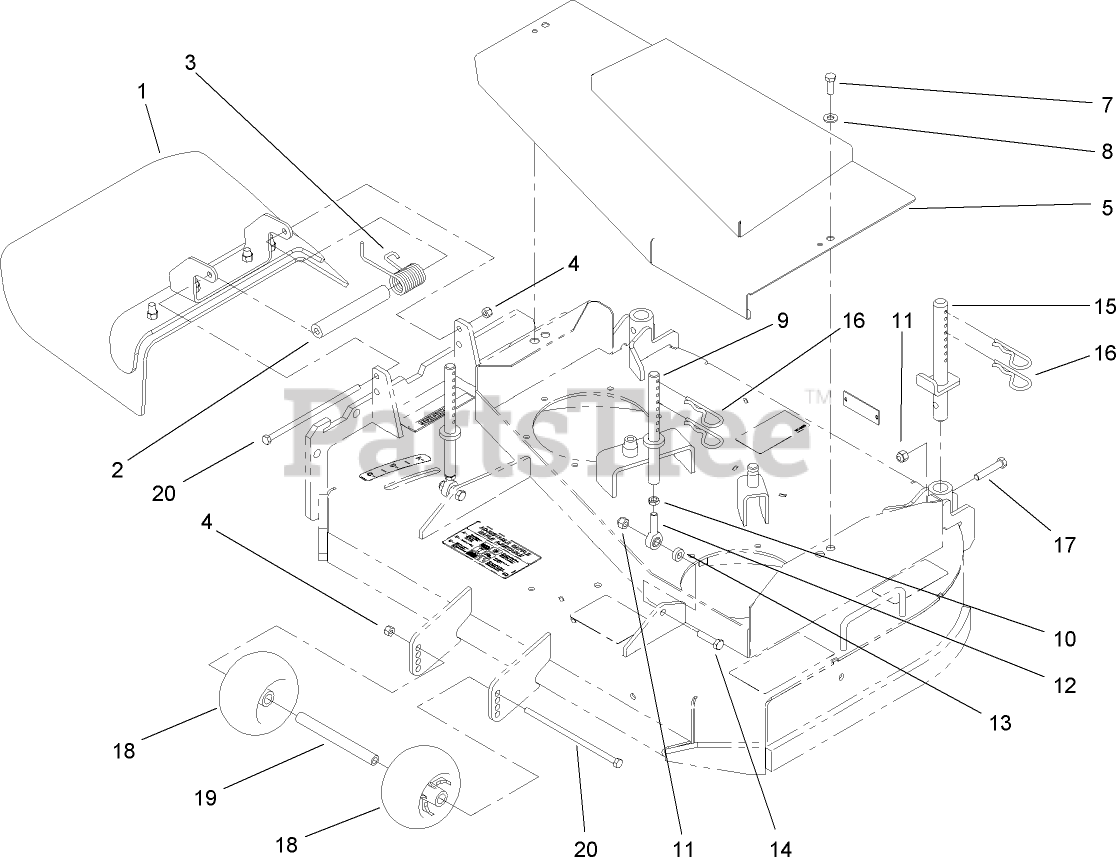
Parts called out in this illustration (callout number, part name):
1	DEFLECTOR ASM
2	SPACER
3	SPRING-TORSION
4	NUT-LOCK, NI
5	COVER ASM
7	SCREW-HH
8	WASHER-FLAT
9	FRONT PIN ASM
10	NUT-HJ
11	NUT-LOCK, NI
12	BALLJOINT
13	SPACER
14	SCREW-HH
15	REAR PIN ASM
16	PIN-HAIR
17	SCREW-HH
18	ROLLER-SCALP, ANTI
19	SPACER-WHEEL
20	SCREW-HH
